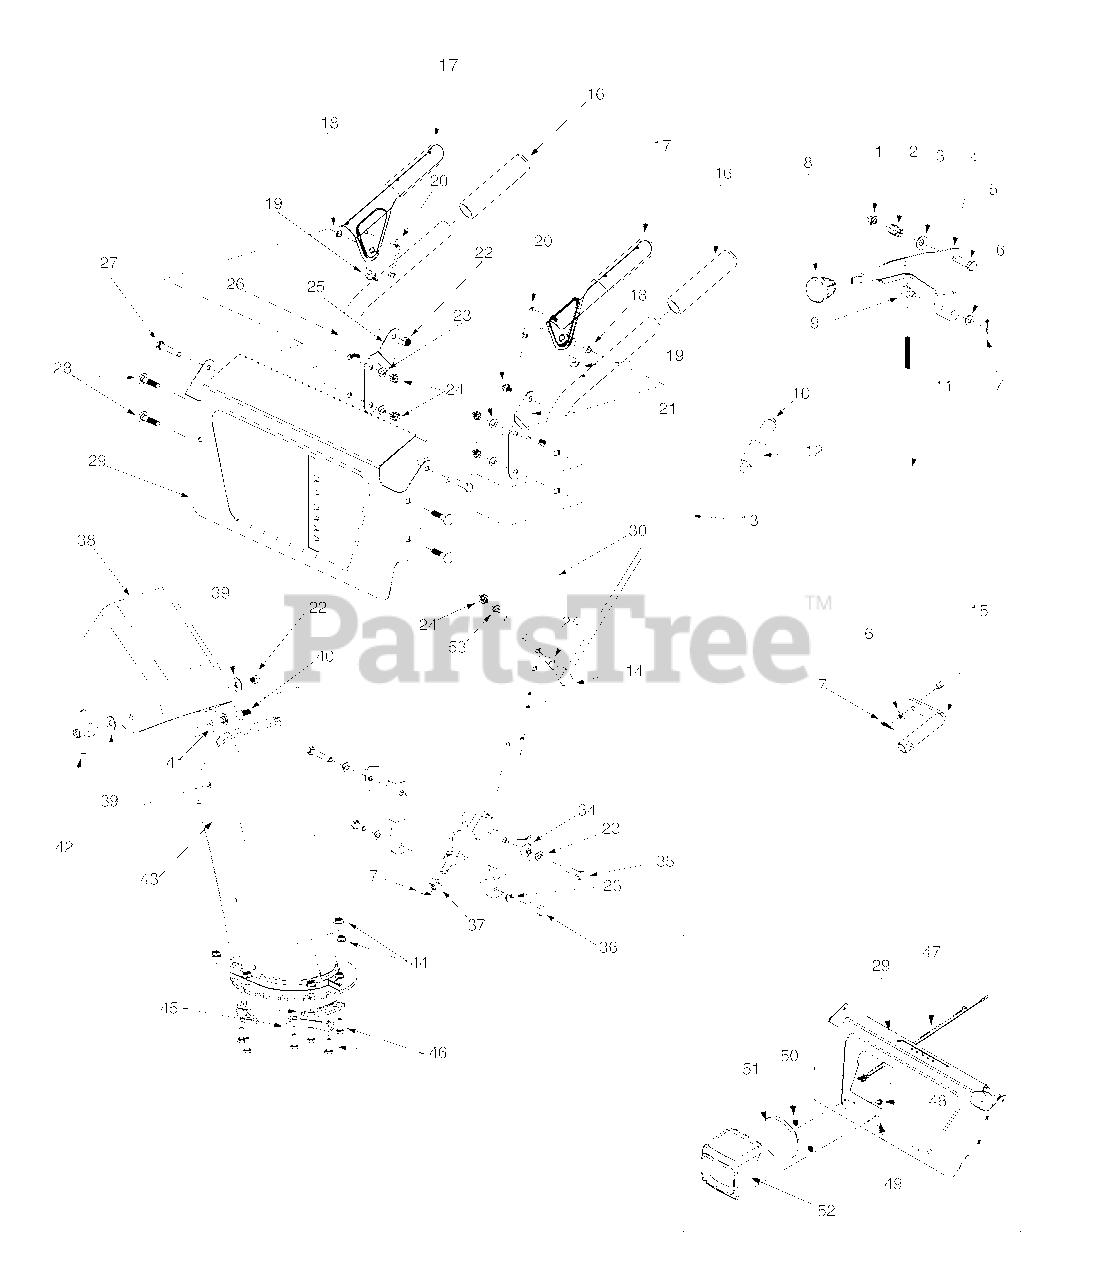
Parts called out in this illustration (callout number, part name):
1	Jam Lock Nut 3/8-24
2	Compression Spring
3	Bell Washer
6	Flat Washer
7	Cotter Pin
8	Shift Knob
9	Ferrule
10	Push Cap
11	Shift Rod
12	Chute Knob
13	Chute Directional Control
14	Eyebolt
17	Clutch Lever Assy LH
18	Spacer
19	Rubber Bumper
20	"Z" Fittings For Control Cables
23	Lock Washer 5/16
24	Hex Nut 5/16-18
28	Carriage Bolt 5/16-18 x 1.50
35	Hex Cap Screw 5/16-18 x 2.0
36	Hex Cap Screw 5/16-18 x .75
37	Flat Washer
38	Upper Chute
39	5/16 Washer
40	Carriage Bolt 5/16-18 x .75
41	Carriage Screw 5/16-18 x 1.0
43	Lower Chute
44	Hex Lock Nut 1/4-20
45	Flange Keeper
46	Hex Cap Screw 1/4-20 x .75
47	Round Light Harness
48	Hex Tap Screw 1/4-20 x .625
49	Hex Screw
50	Hex Nut
51	Headlight 18 Watts
52	Headlight Cover
53	Bell Washer
